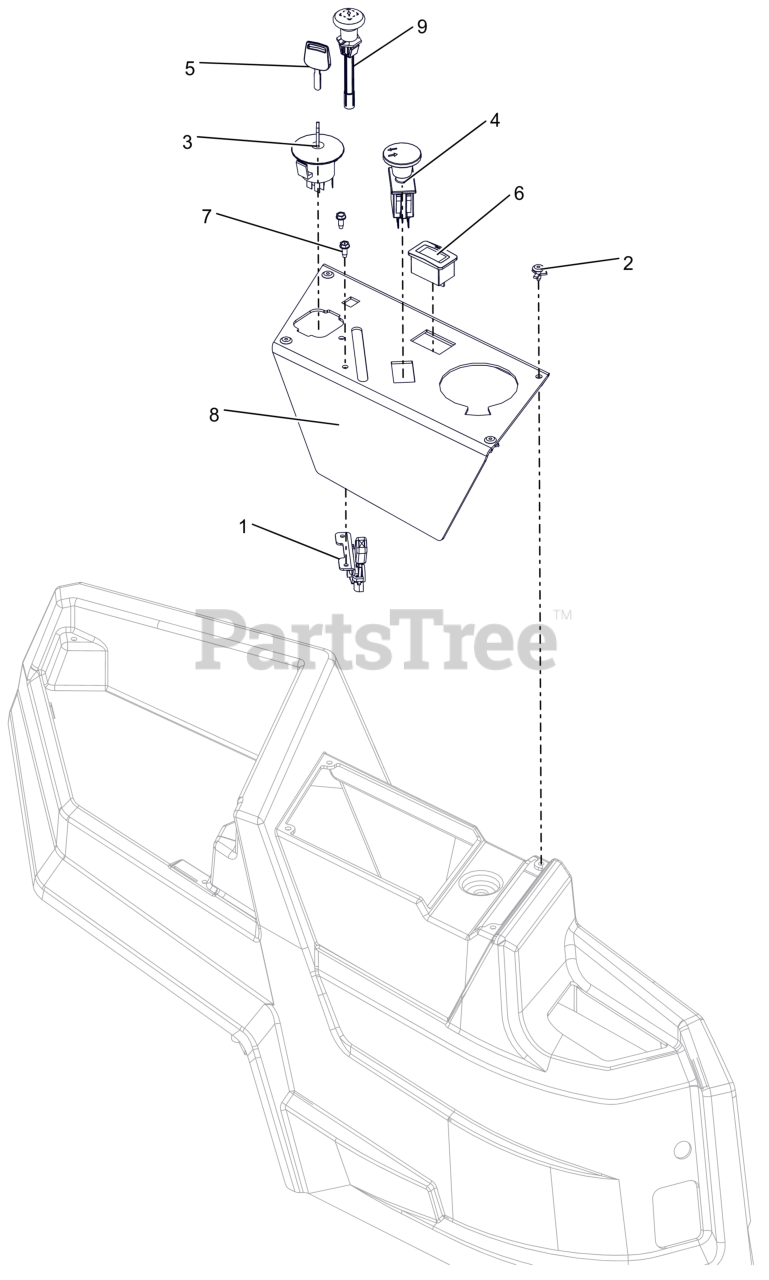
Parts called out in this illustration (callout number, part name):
1	CABLE - THROTTLE CONTROL
2	RIVET, PLASTIC .195 DIA.
3	KEYSWITCH-IGNITION 4 POS
4	SWITCH, CLUTCH (YELLOW)
5	KEY, IGNITION
6	HOUR METER
7	SCR,TAP #10-24X.50 HWH TR ZCC
8	PANEL, CONTROL
9	CABLE - CHOKE, SNAP-IN
